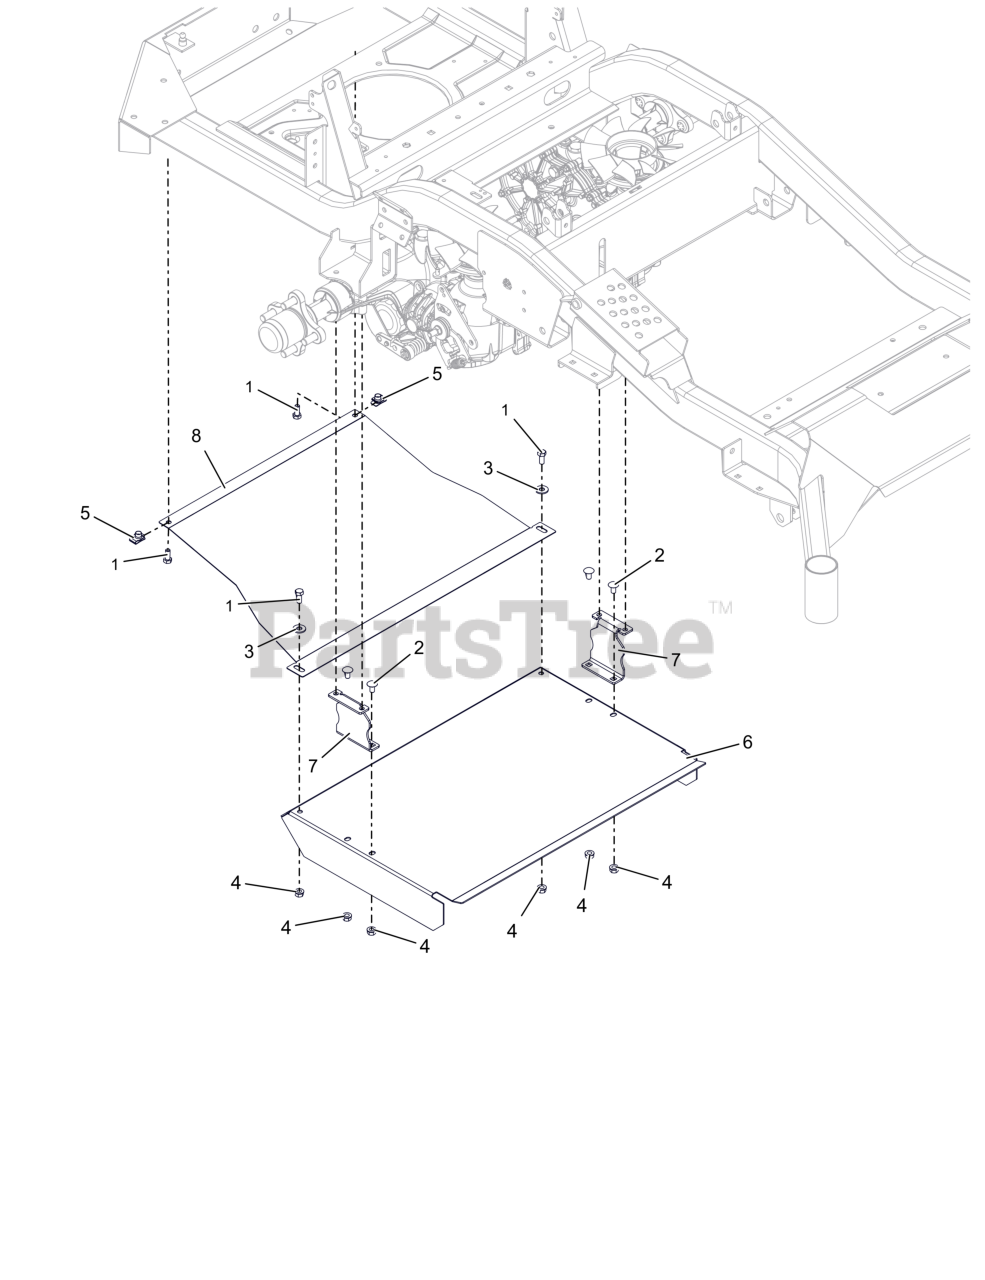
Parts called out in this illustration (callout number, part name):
1	BLT,HEX .31-18X.75 G5 ZCC
2	BLT, RHSSN .31-18X.625 G5 ZCC
3	WSHR,FLT .375X.875X.083 ZCC
4	NUT,LK-CTR-FLG .31-18 GF ZCC
5	NUT-CLIP RETAINER 5/16-18X.56
6	DEFLECTOR- TRANSAXLE
7	BRKT, DEFLECTOR SUPPORT
8	DEFLECTOR, UNDERBODY
